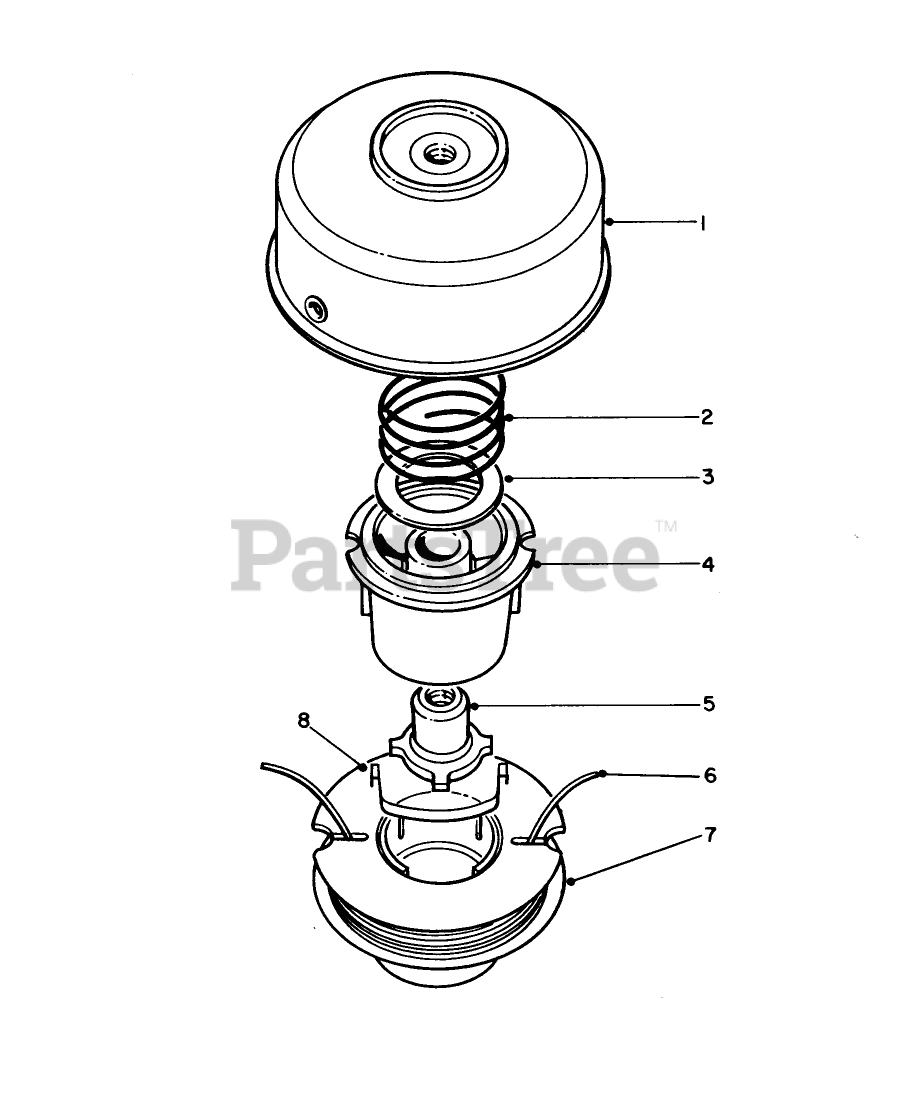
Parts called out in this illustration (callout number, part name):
2	SPRING
3	WASHER-FLAT
4	SPOOL CORE
5	LH DRIVER
